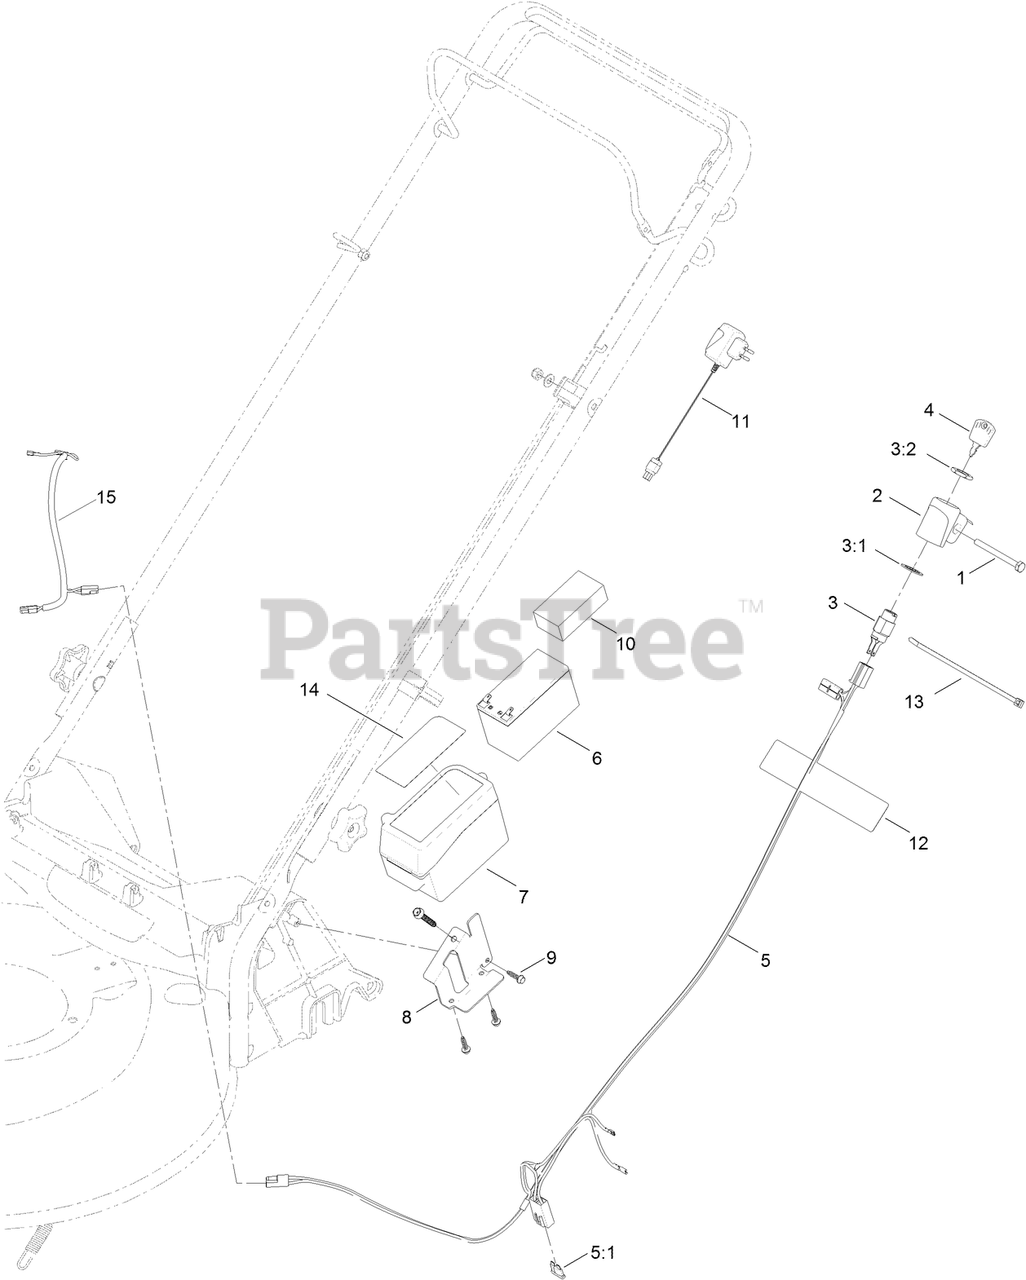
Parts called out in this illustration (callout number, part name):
1	SCREW-HH
2	MOUNT-SWITCH
3	STARTER SWITCH ASM
3:1	WASHER-LOCK
3:2	NUT-HH
5	HARNESS-WIRE
5:1	FUSE-40 AMP
6	BATTERY-NONSPILLABLE, 12 V
7	BATTERY BOX ASM
8	BRACKET-BATTERY
9	SCREW-HWH
10	FOAM-BATTERY, TOP
12	DECAL-WARNING
13	TIE-CABLE
14	DECAL-BOX, BATTERY
15	HARNESS-WIRE
